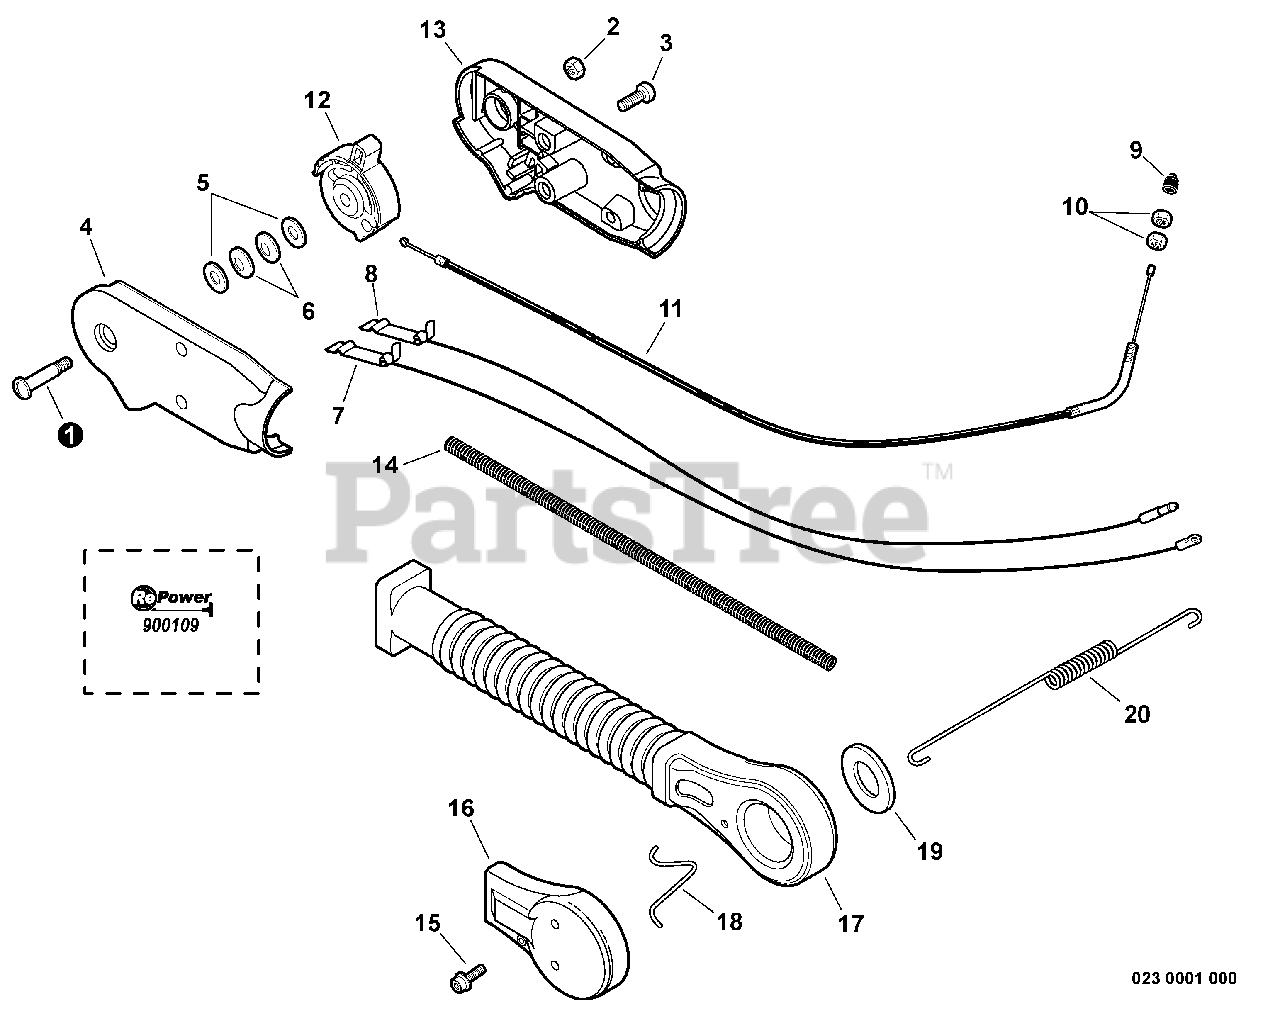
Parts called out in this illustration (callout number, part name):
2	NUT, LOCK 4
4	GRIP, LEFT THROTTLE
5	WASHER 6.5×15.5×0.6
6	WASHER, FRICTION 6.6×14.3
8	LEAD - IGNITION
9	CAP, DUST
10	NUT 6 MM
11	CABLE, THROTTLE
12	LEVER, THROTTLE
13	GRIP, RIGHT THROTTLE
14	TUBE, FLEXIBLE
15	BOLT 5×20
16	BRACKET, LEFT CONTROL ARM
17	ARM, THROTTLE CONTROL
18	HOLDER, SPRING
19	WASHER 45
20	SPRING, TENSION
21	THROTTLE CONTROL KIT - HIP MOUNT
